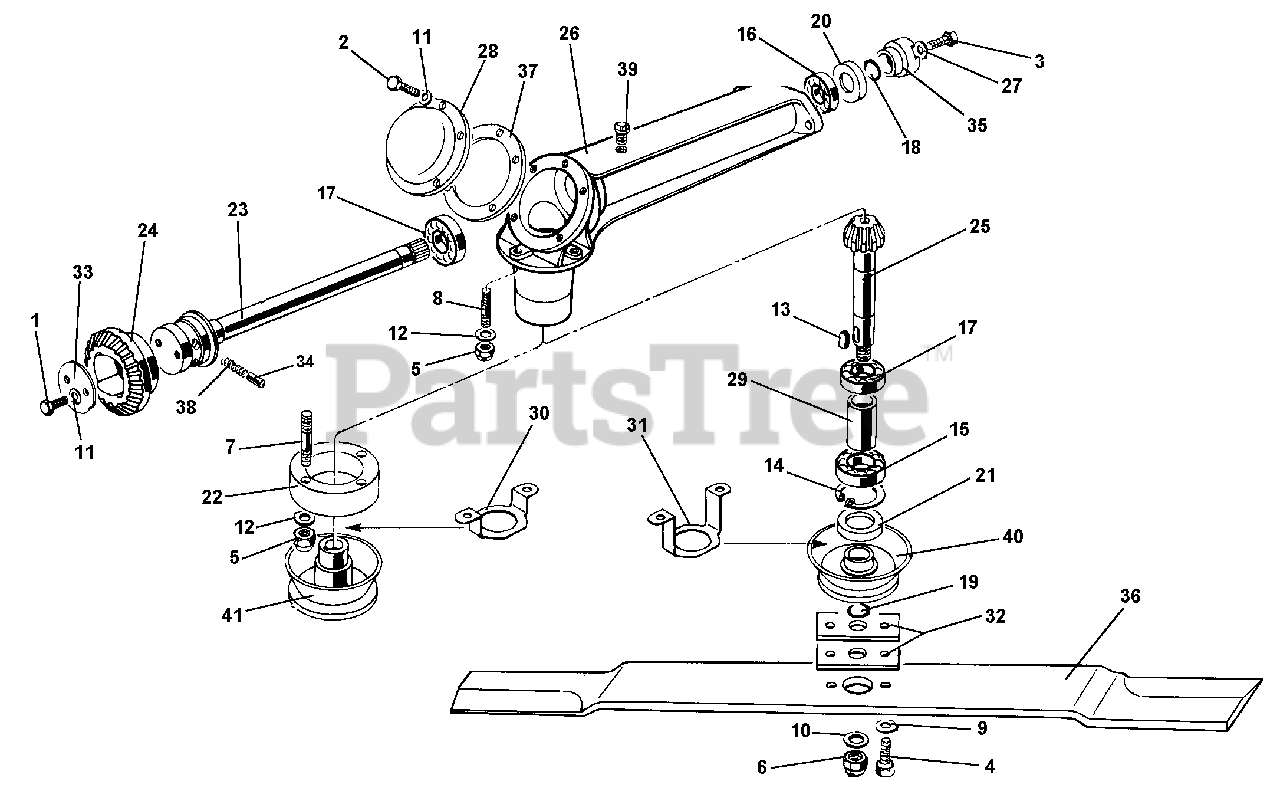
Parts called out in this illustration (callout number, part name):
1	SCREW M6X12
2	SCREW TE M6X16
3	SCREW TE M6X20
4	SCREW M14X45
5	NUT, SELF LOCKING M8
6	NUT, SELF LOCKING M18X1.5
8	STUD M8X40X14X14
9	SUPER WASHER
10	SUPER WASHER
11	WASHER, LOCK 6.4
12	WASHER, LOCK 8.4
13	KEY, 6X6X20
14	CIRCLIP, INTERNAL D 62
15	BEARING 25X62X17
16	BEARING 25X47X12
17	BEARING 25X52X15
18	"O" RING 18.64X3.53
19	"O" RING 25X3.53
20	OIL SEAL 35X47X7
21	OIL SEAL 40X62X7
23	SHAFT FOR GEAR
24	RING BEVEL GEAR
25	BLADE PINION SHAFT
26	MOWER CASING
27	WASHER 7X25X4
30	OIL SEAL PROTECTOR
31	OIL SEAL PROTECTOR
32	BLADE SPACER
33	DISC, GEAR LOCKING
39	BREATHER CAP 1/4
40	BLADE HOLDER HUB
41	BLADE HOLDER HUB
